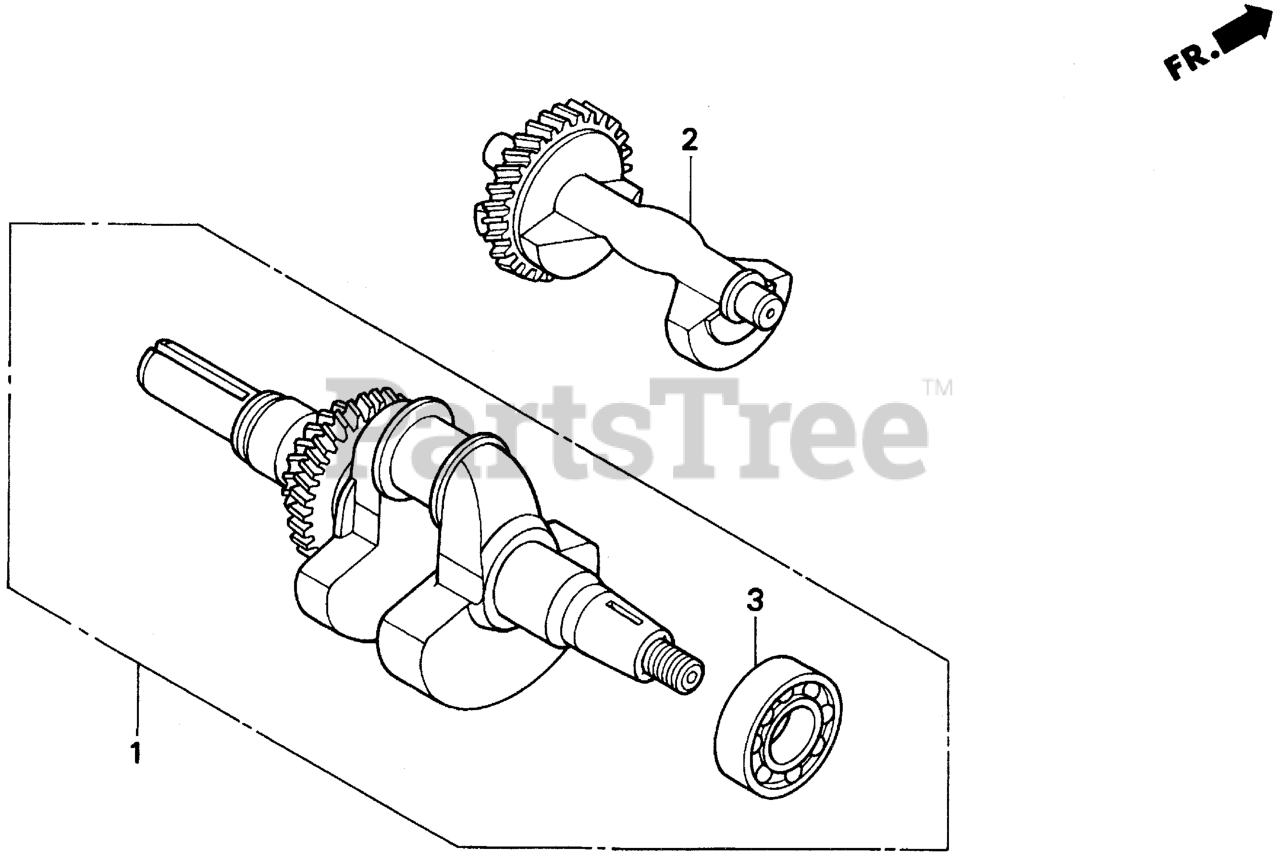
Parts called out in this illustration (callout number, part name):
1	CRANKSHAFT (E-TYPE) (NOT AVAILABLE)
1	CRANKSHAFT
2	WEIGHT, BALANCER
3	BEARING, RADIAL BALL (6207)
